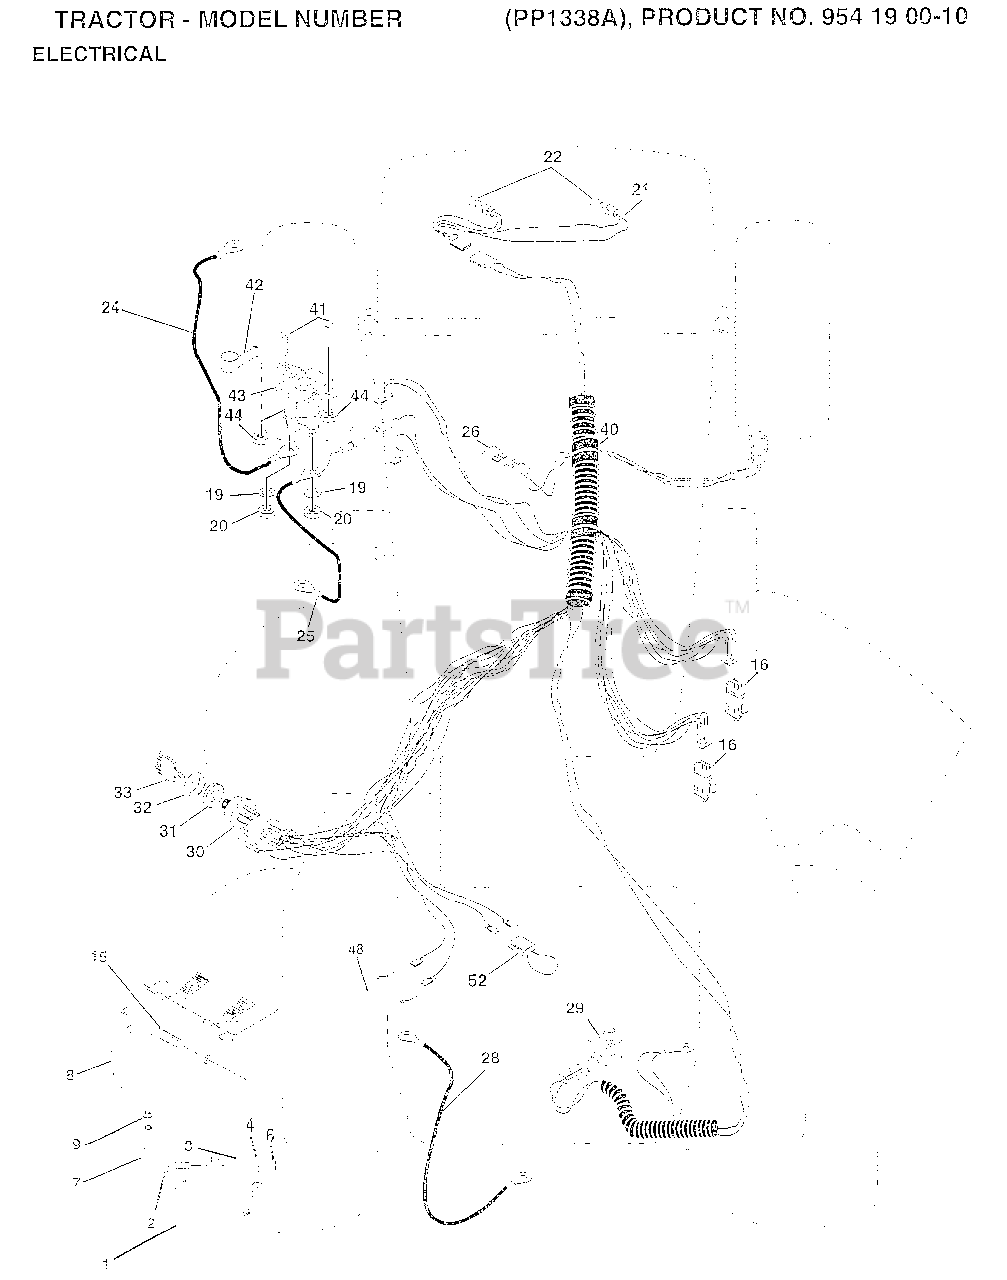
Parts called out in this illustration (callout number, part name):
2	BOLT LT
3	WASHER
4	LOCKWASHER
7	TUBE T
8	"CASE,BATTERY.MECH"
9	HOSE CLAMP T
15	FASTNER.SNAP-IN
16	SWITCH INTERLOCK
20	NUT
21	"HARNESS,LIGHT SOC"
22	HEADLAMP BULB
24	CABLE ASM.
25	CABLE.BTRY.6GA.RD
26	FUSE HYT
28	CABLE T
29	SWITCH SEAT
30	SWITCH IGN 4POS
31	NUT IGNITION
32	COVER KEY SWITCH
33	KEY
40	HARNESS-IGNITION
41	BOLT HXHD FIN
44	NUT HXKEP 1/4X20
48	ADAPTER AMMETER
52	PROTECTION LOOP
